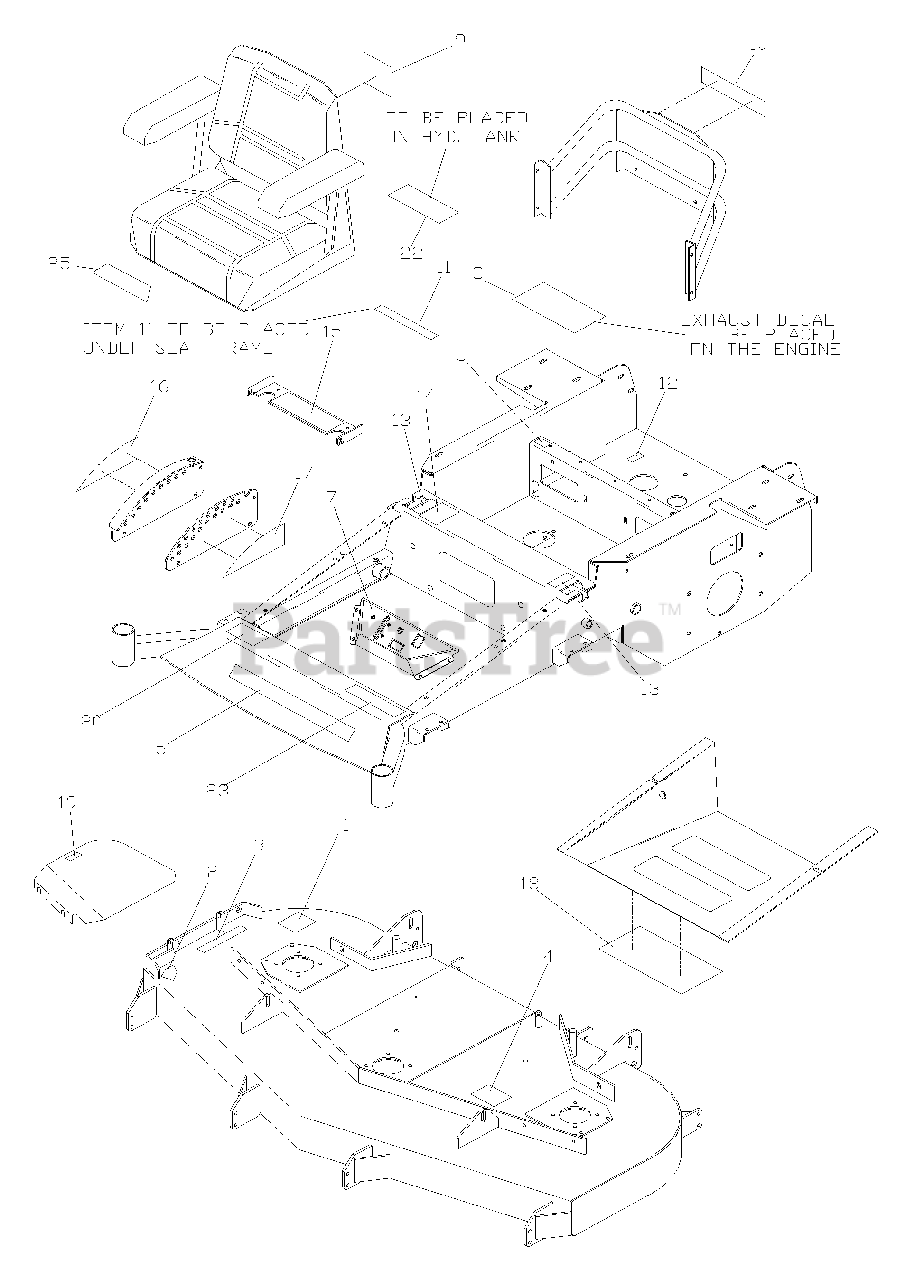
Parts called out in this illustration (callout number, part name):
1	DECAL, ANTI SCALP
2	DECAL, DANGER
3	DECAL, WARNING
4	DECAL, BELT ROUTING
5	DECAL, HUSQVARNA
6	DECAL, FUEL VALVE
6	DECAL, FUEL VALVE STD
7	DECAL, CONSOLE
8	DECAL, EXHAUST
9	DECAL, CROWN
10	DECAL, HUSQVARNA
11	DECAL, BATTERY
12	DECAL, PROP 65
13	DECAL, MOTION CONTROL
14	DECAL, THROWN OBJECTS
15	DECAL, WARNING
16	DECAL, HEIGHT
17	DECAL, HEIGHT
18	DECAL, SERVICE
19	DECAL, NO STEP
20	DECAL, NASCAR
21	DECAL, 7226 EFI
21	DECAL, 5221
21	DECAL, 5223
21	DECAL, 5223L
21	DECAL, 5225
21	DECAL, 6123L
21	DECAL, 6123
21	DECAL, 6125
21	DECAL, 6126 EFI
22	DECAL, MOBIL 1
23	DECAL, XP SERIES
24	DECAL, BELT DRIVES
25	DECAL, HUSQVARNA
